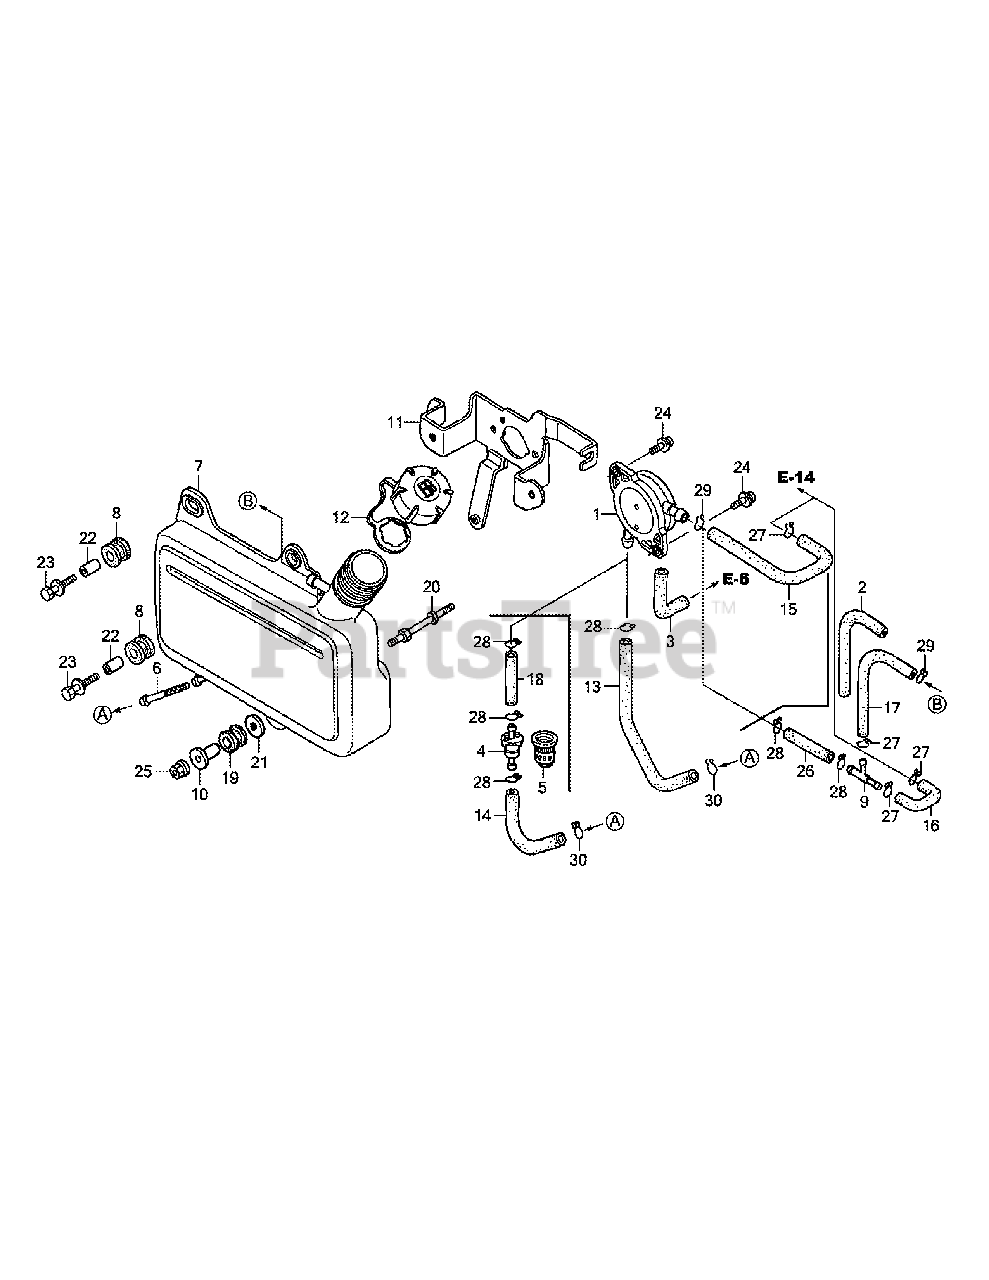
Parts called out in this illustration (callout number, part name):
1	Fuel Pump Assembly
2	Supporter Rubber, 107mm
3	Tube, Diaphragm
4	Fuel Strainer
5	Strainer, Suspension
7	Tank Mounting Rubber, B
10	Stay A, Fuel Tank
11	Fuel Cap Assembly
12	Fuel Tank Tube
14	Fuel Return Tube
15	Fuel Pump Tube
16	Rear Fender Cushion
17	Fuel Tank Stud Bolt, 30mm
18	Washer, 6Mm
19	Collar, 14 X 6.1
20	Bolt-Washer, 6 X 25
21	Screw-Washer, 5 X 14
22	Nut, Flange, 6mm
23	Fuel Tube, 5.3 X 33
24	Tube Clip, B8
25	Tube Clip, B10
26	Tube Clip, C9
27	Tube Clip, C11
